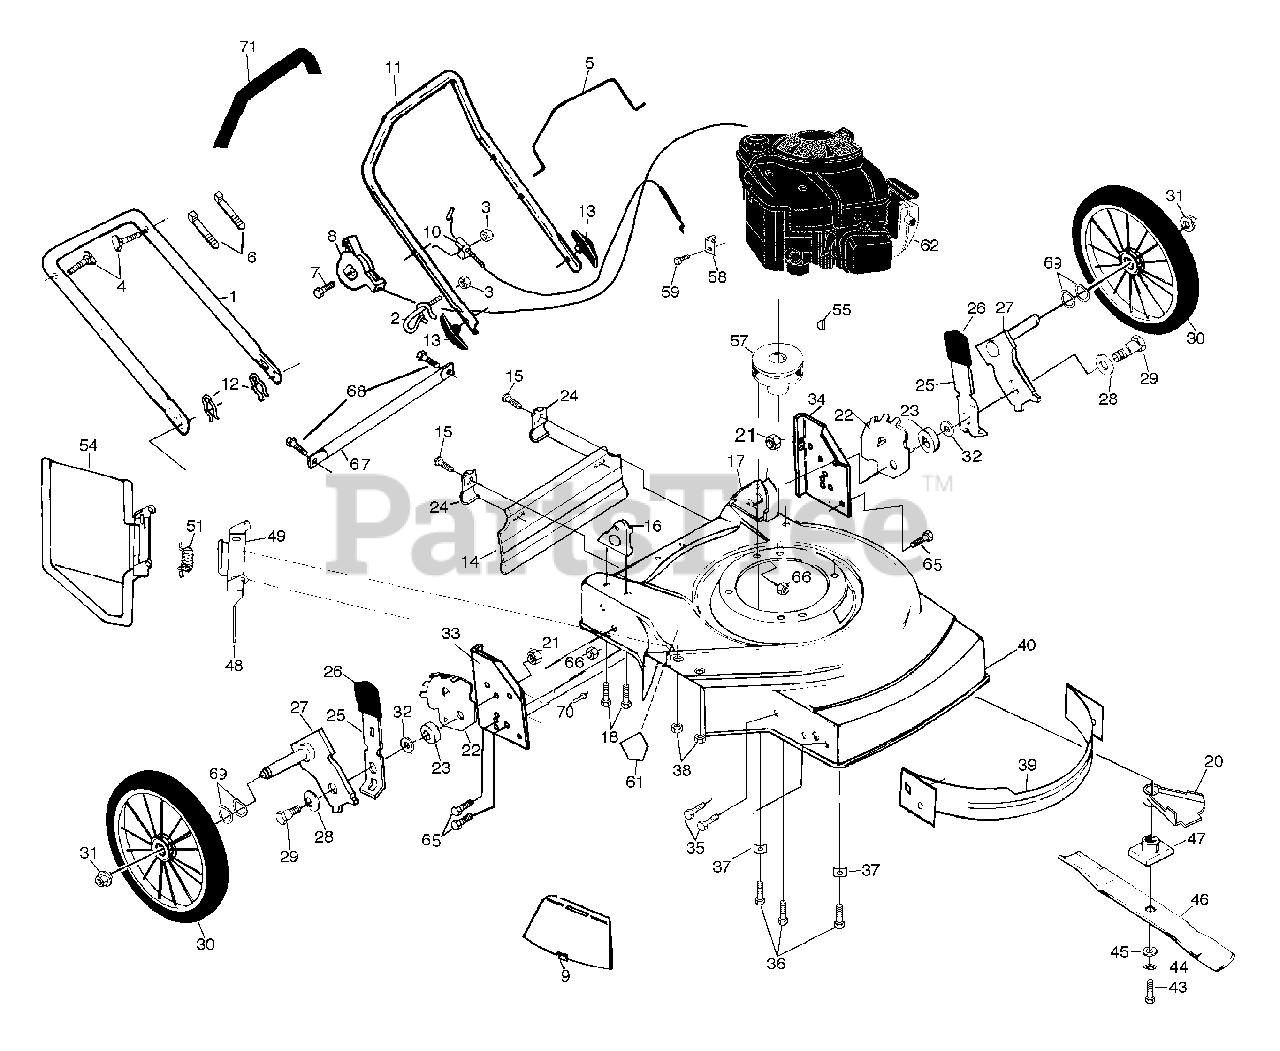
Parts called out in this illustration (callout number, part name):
1	Lower Handle
2	Rope Guide
3	Locknut 1/4-20
4	Handle Bolt
5	Control Bar
6	Wire Ties
7	Hex Washer Head Screw 1/4-20 x 2-1/8
8	Throttle Control
9	Mulcher Plate
10	Engine Zone Control Cable
11	Upper Handle
12	Hairpin Cotter
13	Handle Knobs
14	Rear Skirt
15	Hex Head Screw
16	Handle Bracket Assembly (Right)
17	Handle Bracket Assembly (Left)
18	Screw 5/16-18 x 3/4
20	Debris Shield
21	Locknut
22	Wheel Adjusting Bracket
23	Spacer
24	Skirt Bracket
25	Selector Spring
26	Selector Knob
27	Axle Arm Assembly
28	Belleville Washer
29	Shoulder Bolt 3/8-16
30	Wheel & Tire Assembly (Rear)
31	Flanged Locknut 3/8-16
32	Flat Washer
33	Wheel Support Bracket (RT)
34	Wheel Support Bracket (LT)
36	Thread Rolling Screw 3/8-16 x 1
37	Engine Washer
38	Nut
39	Front Baffle Kit
40	Mower Housing Kit
43	Hex Head Screw 3/8-24 x 1-3/8 Gr. 8
44	Helical Washer 3/8
45	Hardened Washer
47	Blade Adapter
49	Housing Bracket
51	Torsion Spring
54	Discharge Guard
55	Hi-Pro Key
57	Engine Pulley
58	Cable Clamp
59	Screw #10 x 5/8
61	Danger Decal
66	Nut
67	Support Rod
68	Screw hex Tap. 1/4/20
69	Wave Washer
71	Foam Grip
